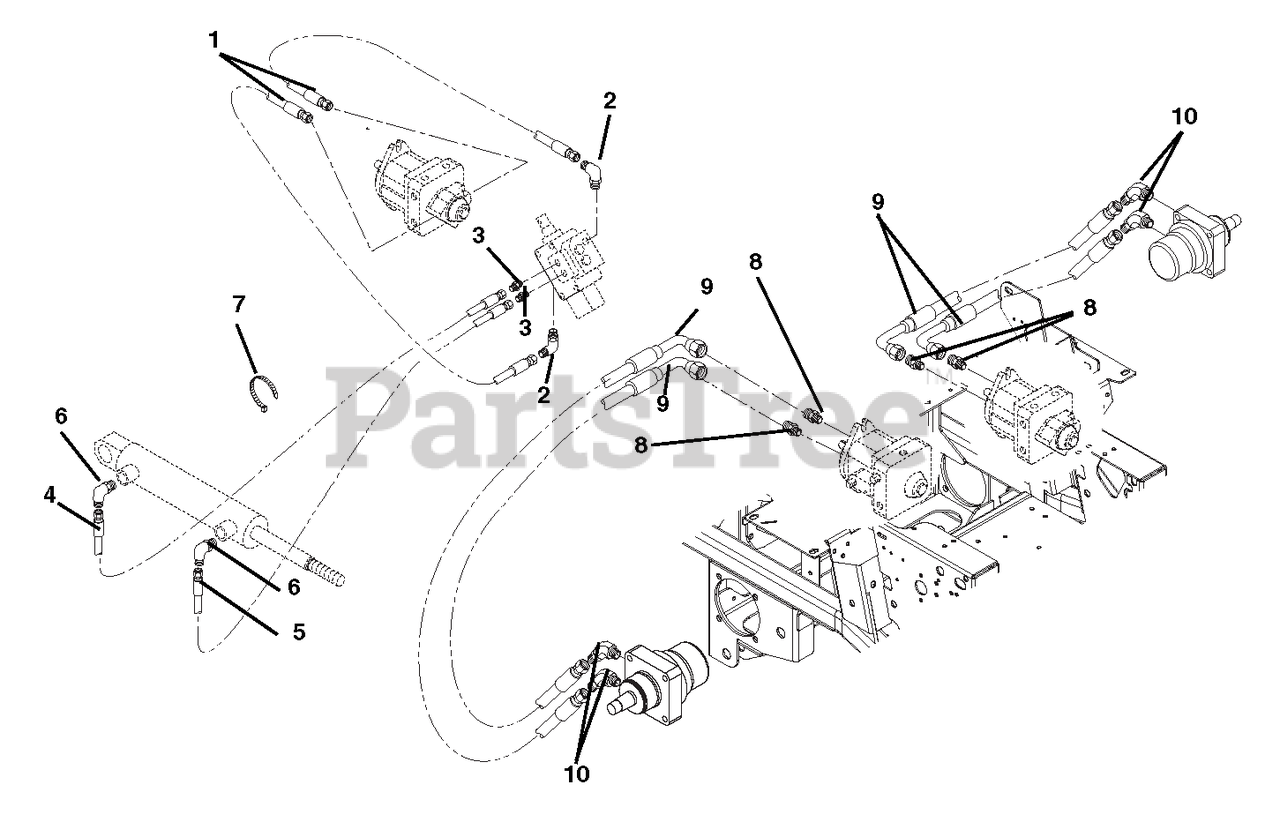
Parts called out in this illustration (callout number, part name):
1	HOSE,HYD.25-22-2K F04F9-F06FO
2	FTG, HYD ELBOW M6F-M8O
3	FITTING, HYD (4-6 F5OLO)
4	HOSE,HYD.25-42-2K F04F0-F04F4
5	HOSE,HYD .25-47-2K F04F0-F04F4
6	FITTING, HYD (4 C5OLO)
7	CABLE TIE LG 5-1/2
8	ADPTR,FACE SEAL 8X8 1/2 O-RING
9	HOSE,HYD .50-17-2K F08F0-F08F9
10	FITTING, HYD (8-10 V5OLO)
